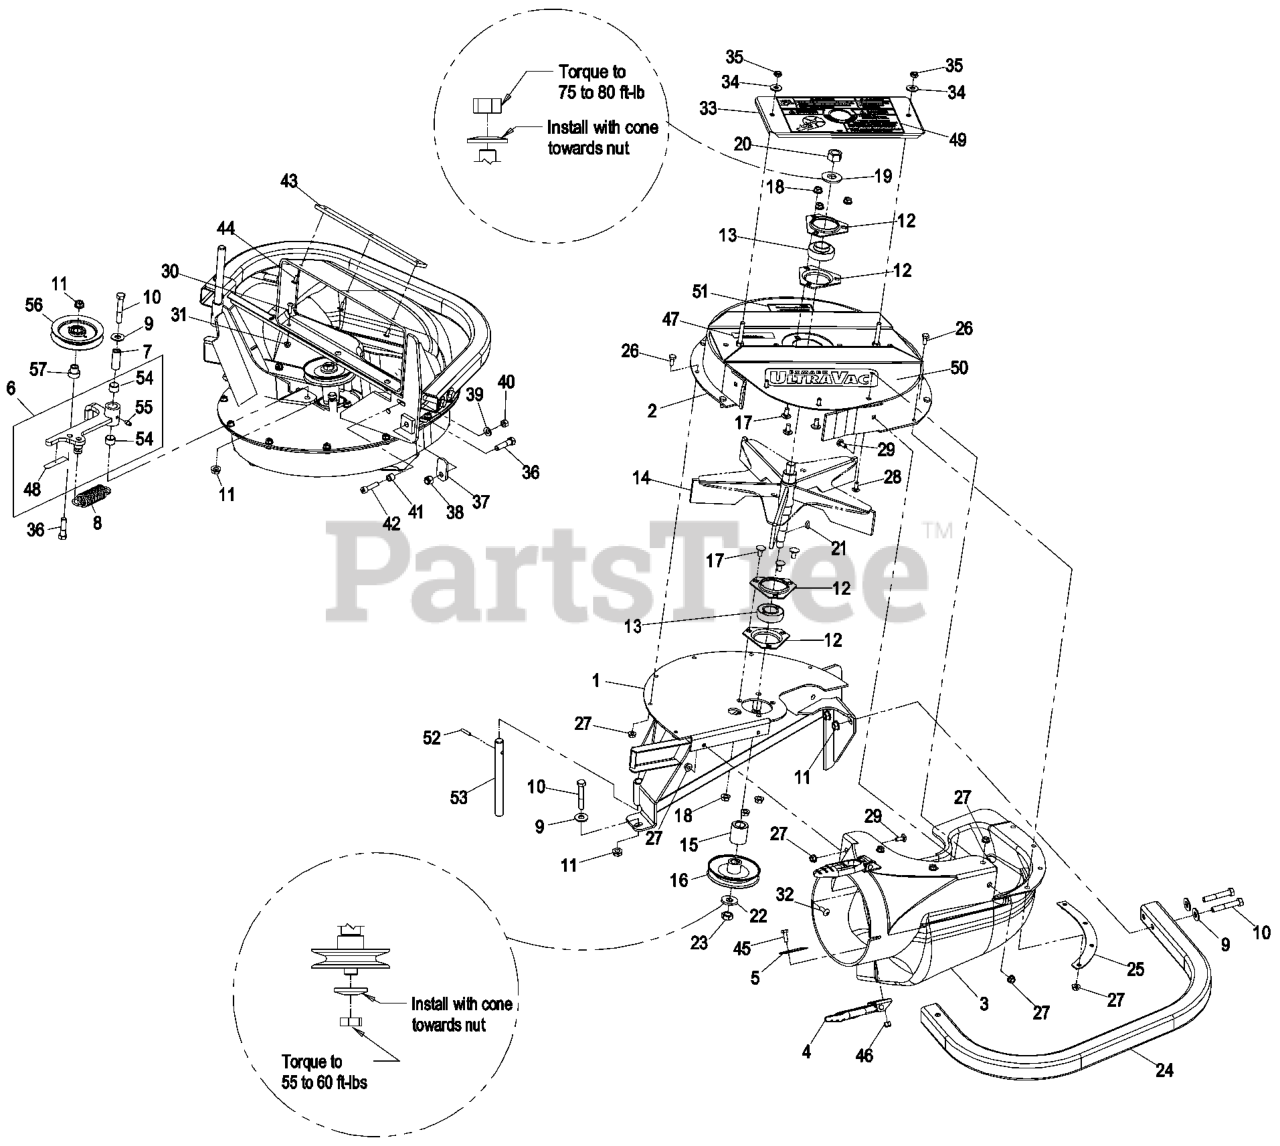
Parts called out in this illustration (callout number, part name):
1	WLD,FRAME LG BLOWER
2	ASM, UPPER HSG
3	ASM,BLOWER CHUTE LZ
4	LATCH-RUBBER
5	PLATE-BACKING
6	ASM, IDLER ARM - SERVICE
7	BUSHING
8	SPRING-IDLER
9	WASHER-FLAT
10	SCREW-HH
11	NUT-HHF, WHIZ
12	HOUSING-FLANGE
13	BEARING
14	IMPELLER
16	SHEAVE
17	SCREW-CARR
19	WASHER-SPRING
20	NUT-HEX
21	KEY-WOODRUFF
22	WASHER-SPRING
23	NUT-JAM
25	PLATE-BACKING, BLOWER
26	SCREW-HH
28	SCREW-CARR
29	BOLT-CARR
30	SCREW-HEAD, TRUSS
33	ASM, BEARING COVER
34	WASHER-FLAT
35	NUT-LOCK, NI
36	SCREW-HH
37	LATCH-CATCHER, GRASS
38	NUT-LOCK, NI
39	WASHER-SPRING
40	NUT-HEX
41	BUSHING, LOCATOR
42	SCREW-HSH
43	PLATE,REINFORCEMENT LARGE
44	RIVET-BLIND
45	SCREW-HH
46	NUT-LOCK, NI
47	DECAL-COVER, MISSING
48	DECAL-WARNING
49	DECAL-WARNING, BLOWER
50	DECAL, ULTRA VAC
51	DECAL,WEIGHT
52	PIN-ROLL
53	SHAFT-CATCHER, GRASS
54	BUSHING
55	FITTING-GREASE
57	HUB,SPACER
